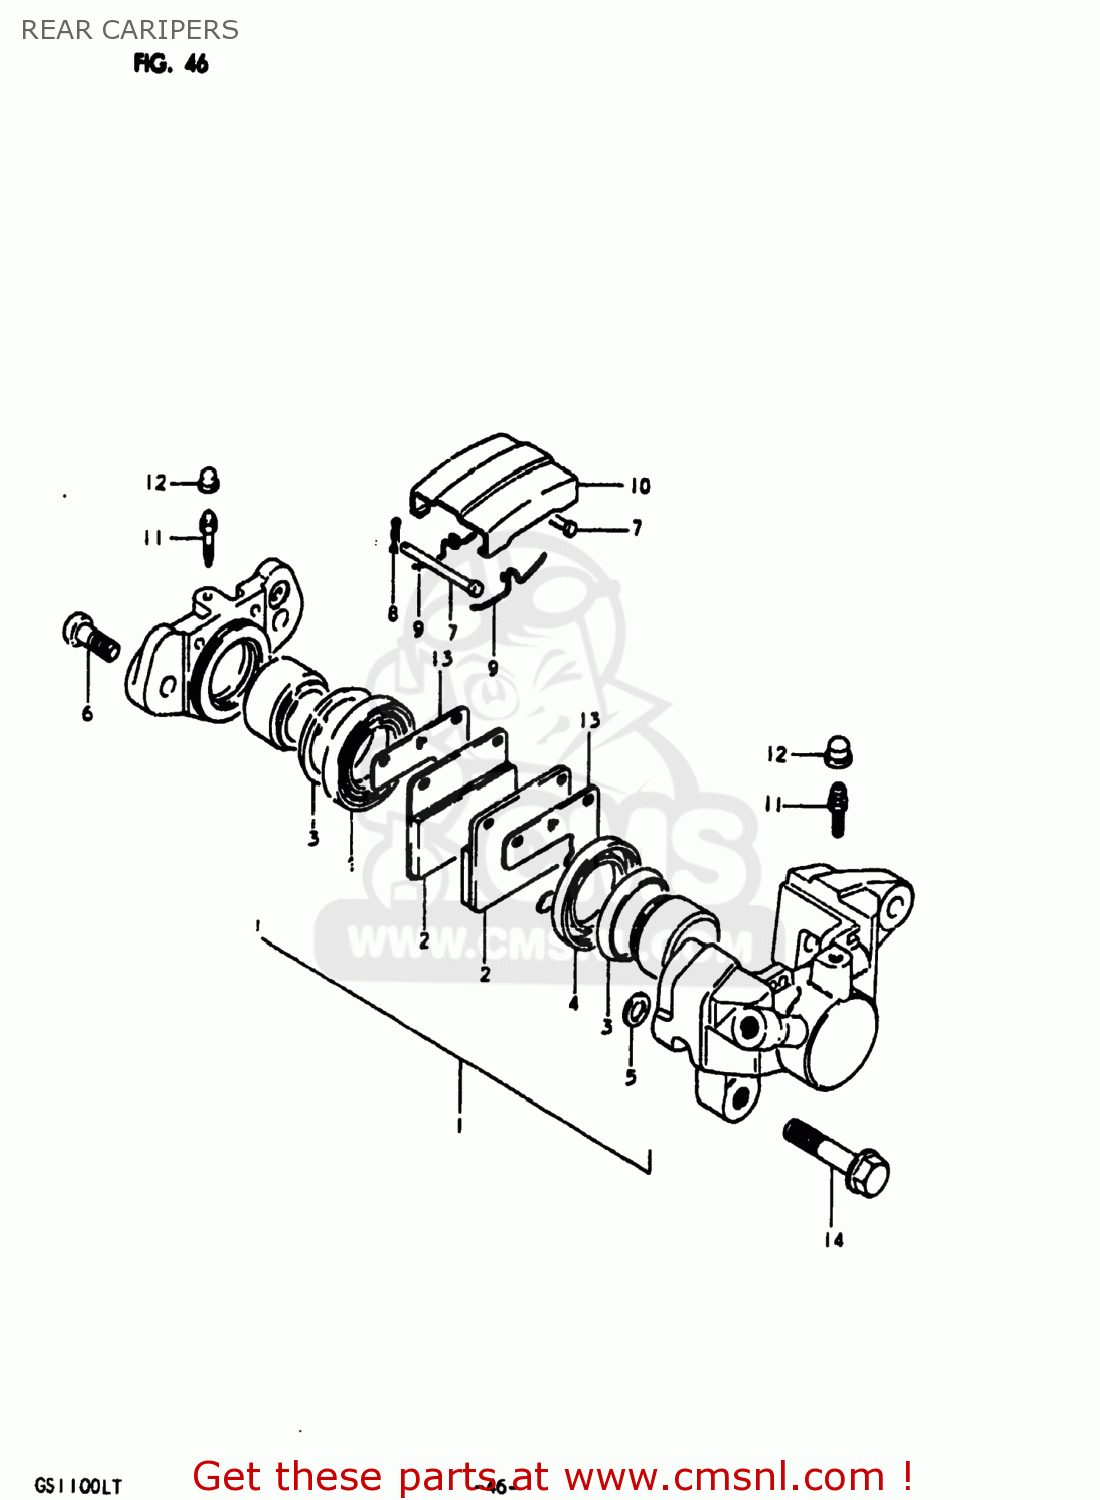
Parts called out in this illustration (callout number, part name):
1	PISTON SET
2	PAD,BRAKE
3	SEAL,PISTON
4	BOOT,PISTON
5	SEAL,PISTON
6	BOLT,HOUSING
7	PIN,PAD
8	CLIP,PAD PIN
9	SPRING
10	COVER,DUST
11	BLEEDER
12	CAP,BREATHER
13	SHIM,RR CALIPER
14	BOLT
